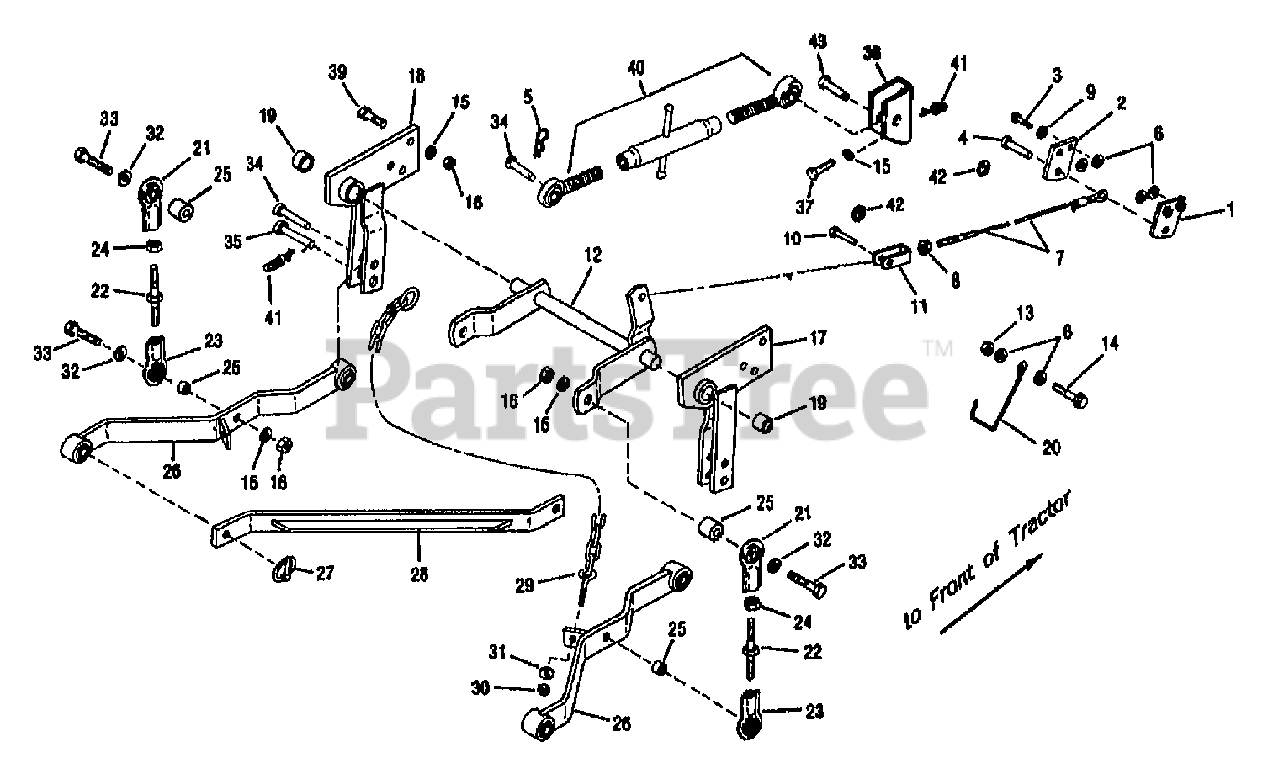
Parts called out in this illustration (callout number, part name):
1	ASSM-LIFT ARM
2	ARM-LIFT
3	SCR-HH 3/8-16X1.5 G5 ZP
4	PIN-CLEVIS .5X1.437 ZP
5	PIN-HITCH .125X2.56 ZP
6	WASHER-.875X.390X.134
7	CABLE-LIFT
8	NUT-HEX/JAM 3/8-16
9	WASHER-LK .375 @ DEPL
10	PIN-CLEVIS .5X1.25
11	YOKE-CABLE
12	ASSM-PIVOT SHAFT
13	NUT-H/LK 3/8-16
14	SCR-HFLK 3/8-16X1.25 ZP
15	WASHER-LK .5
16	NUT-HEX JAM 1/2-13
17	ASSM-HITCH RH
18	ASSM-HITCH LH
20	GUIDE-CABLE
22	ASSM-STUD
24	NUT-JAM
25	SPACER-.656X.512X.297
26	ASSM-LOWER LINK
27	PIN-RETAIN
28	ASSM-SWAG BAR
30	NUT-TOP/LK 5/16-18 ZP
31	WASHER-.88X.343X.1345
32	WASHER-.685X.515X.059
33	SCR-HH 1/2-13X2.25 G5 ZP
34	PIN-CLEVIS .62X2.50 ZP
35	PIN-CLEVIS .75X2.5
37	SCR-HH 1/2-13X1.0 G5 ZP
38	BRACKET-HITCH
39	SCR-HH 1/2-13X1.25 G5 ZP
40	ASSM-UPPER LINK
41	RING-COTTER
42	RING-CIRCLE COTTER
43	PIN-CLEVIS
